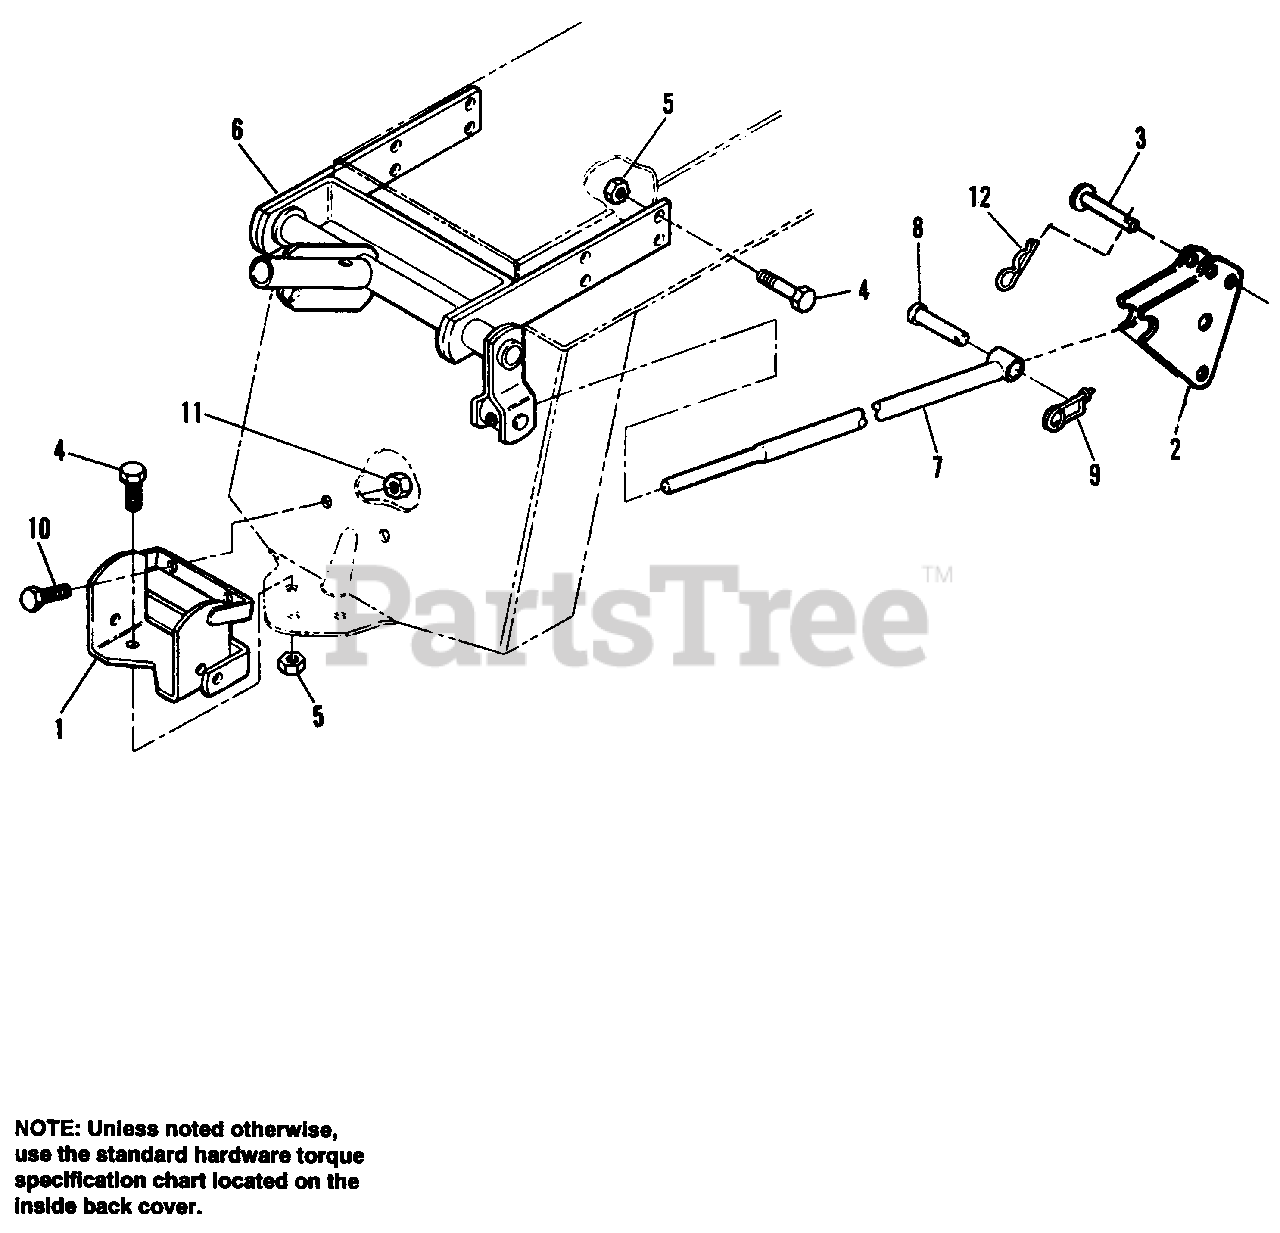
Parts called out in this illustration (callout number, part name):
1	LOWER HITCH ASSY.
2	LIFT LEVER EXTENSION ASSY.
3	PIN, Round Head, Drilled, 1/2 x 2-1/2
4	CAPSCREW, Hex, 1/2-13 x 1-1/2
5	NUT, Hex, Nylon Lock, 1/2-13
6	LIFT SHAFT ASSY.
7	LIFT ROD ASSY.
8	PIN
9	CLIP PIN, Safety
10	CAPSCREW, Hex, 5/16-18 x 1
11	NUT, Hex, Lock, Esna, 5/16-18
